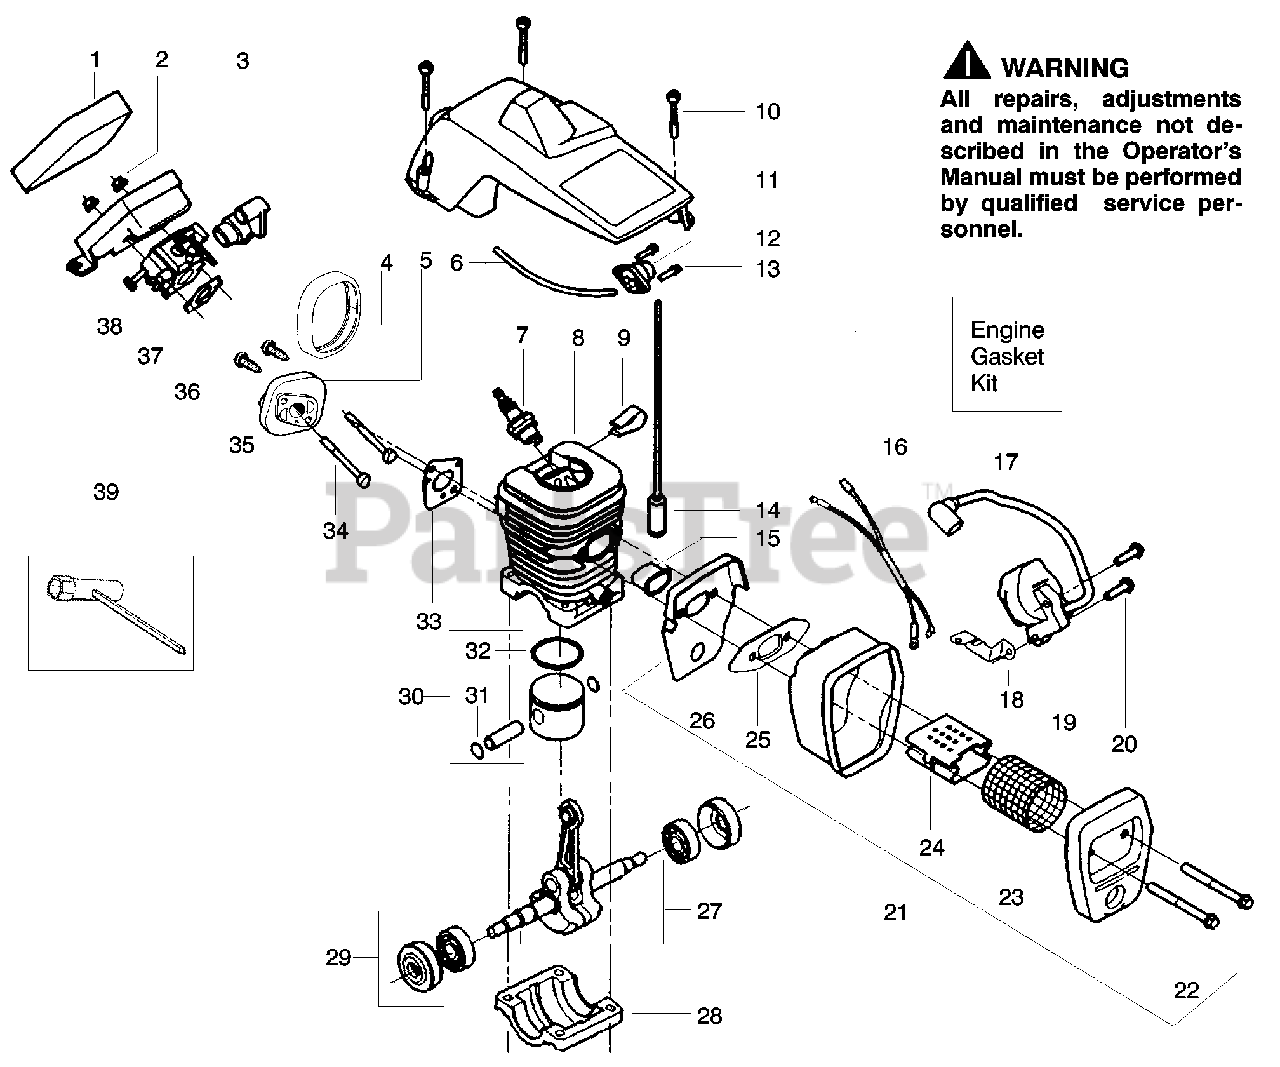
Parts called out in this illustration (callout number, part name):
1	Foam-Air Filter
3	Grommet-Carb Adjust
4	Seal-Carb Adapter
5	Adapter-Carb.
6	Kit- Fuel Line (Small)
7	Spark Plug (RCJ-7Y)
8	Kit-Cylinder
9	Clip-High Tension Lead
11	Shield-Cylinder
12	Assy-Air Purge
14	Assy-Fuel Pick-up
15	Insulator-Heat
16	Assy.-Wire Harness
17	Kit-Engine Gasket
18	Strap-Ground
19	Module-Ignition
21	Assy-Muffler
23	Screen-Spark
24	Diffuser-Muffler
25	Gasket-Muffler (kit)
26	Backplate-Muffler
27	Assy.-Crankshaft
28	Cap-Crankcase
29	Assy.-Seal & Bearing
30	Kit-Piston
31	Retainer-Piston Pin
32	Ring-Piston
33	Gasket-Adapter (kit)
36	Gasket-Carb. (kit)
37	Kit-Carburetor (WT-324)
37	Kit-Carburetor (WT-624)
38	Housing-Air Filter
39	Wrench-Bar
